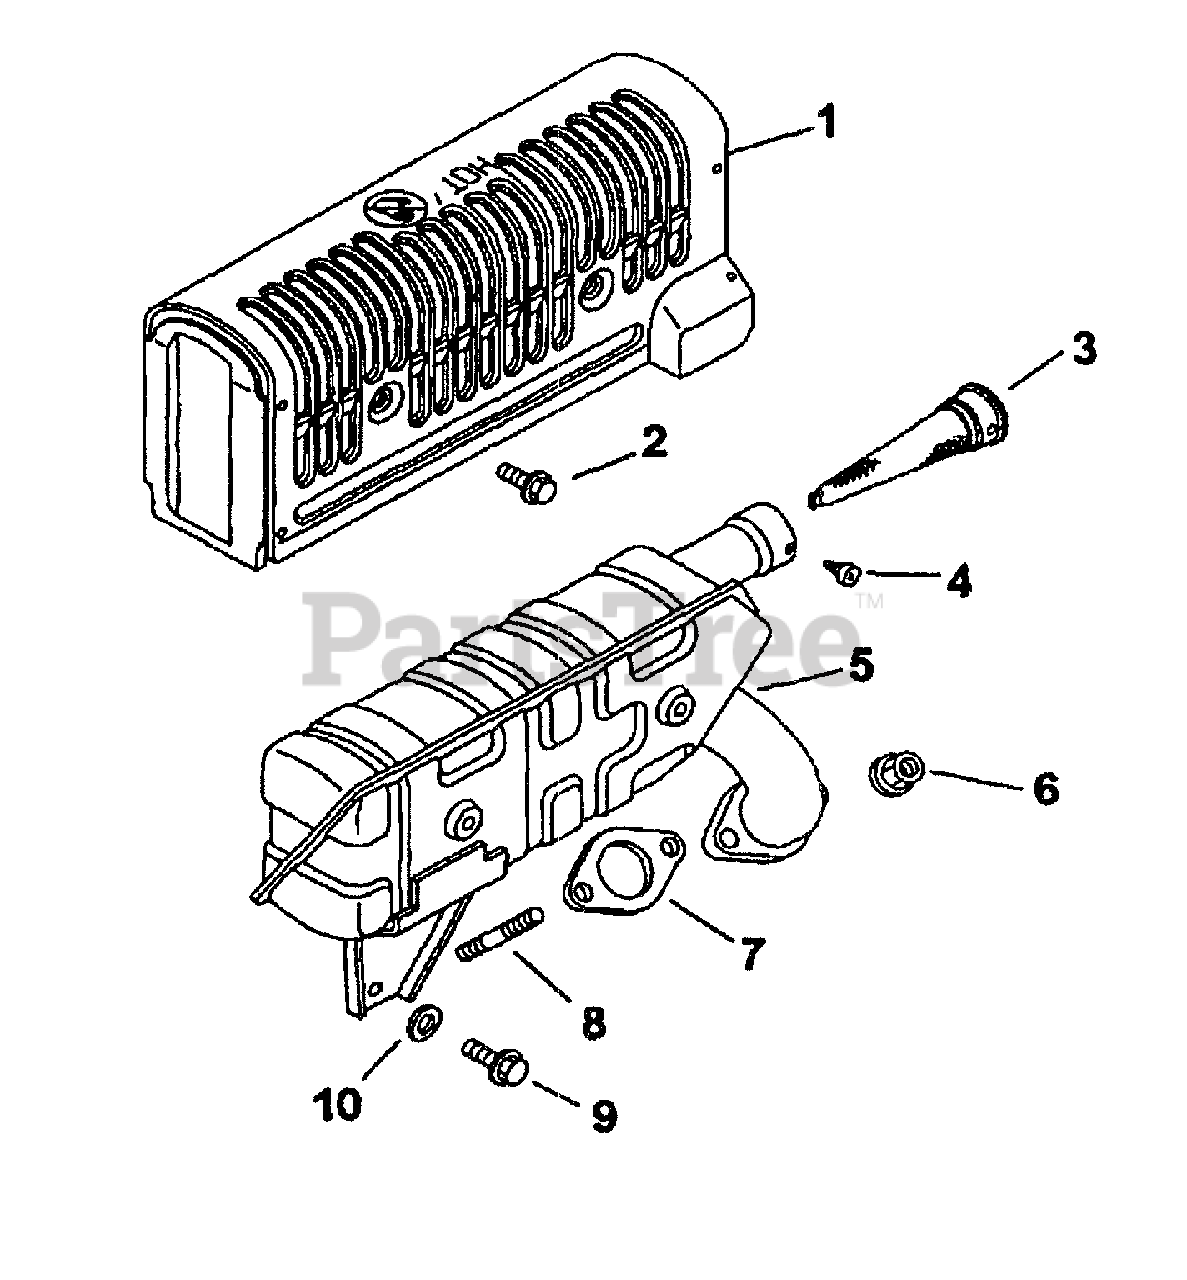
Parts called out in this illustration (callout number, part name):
1	Guard, Kit Muffler
3	Arrestor, Spark
7	Gasket, Exhaust
8	Stud, Exhaust
